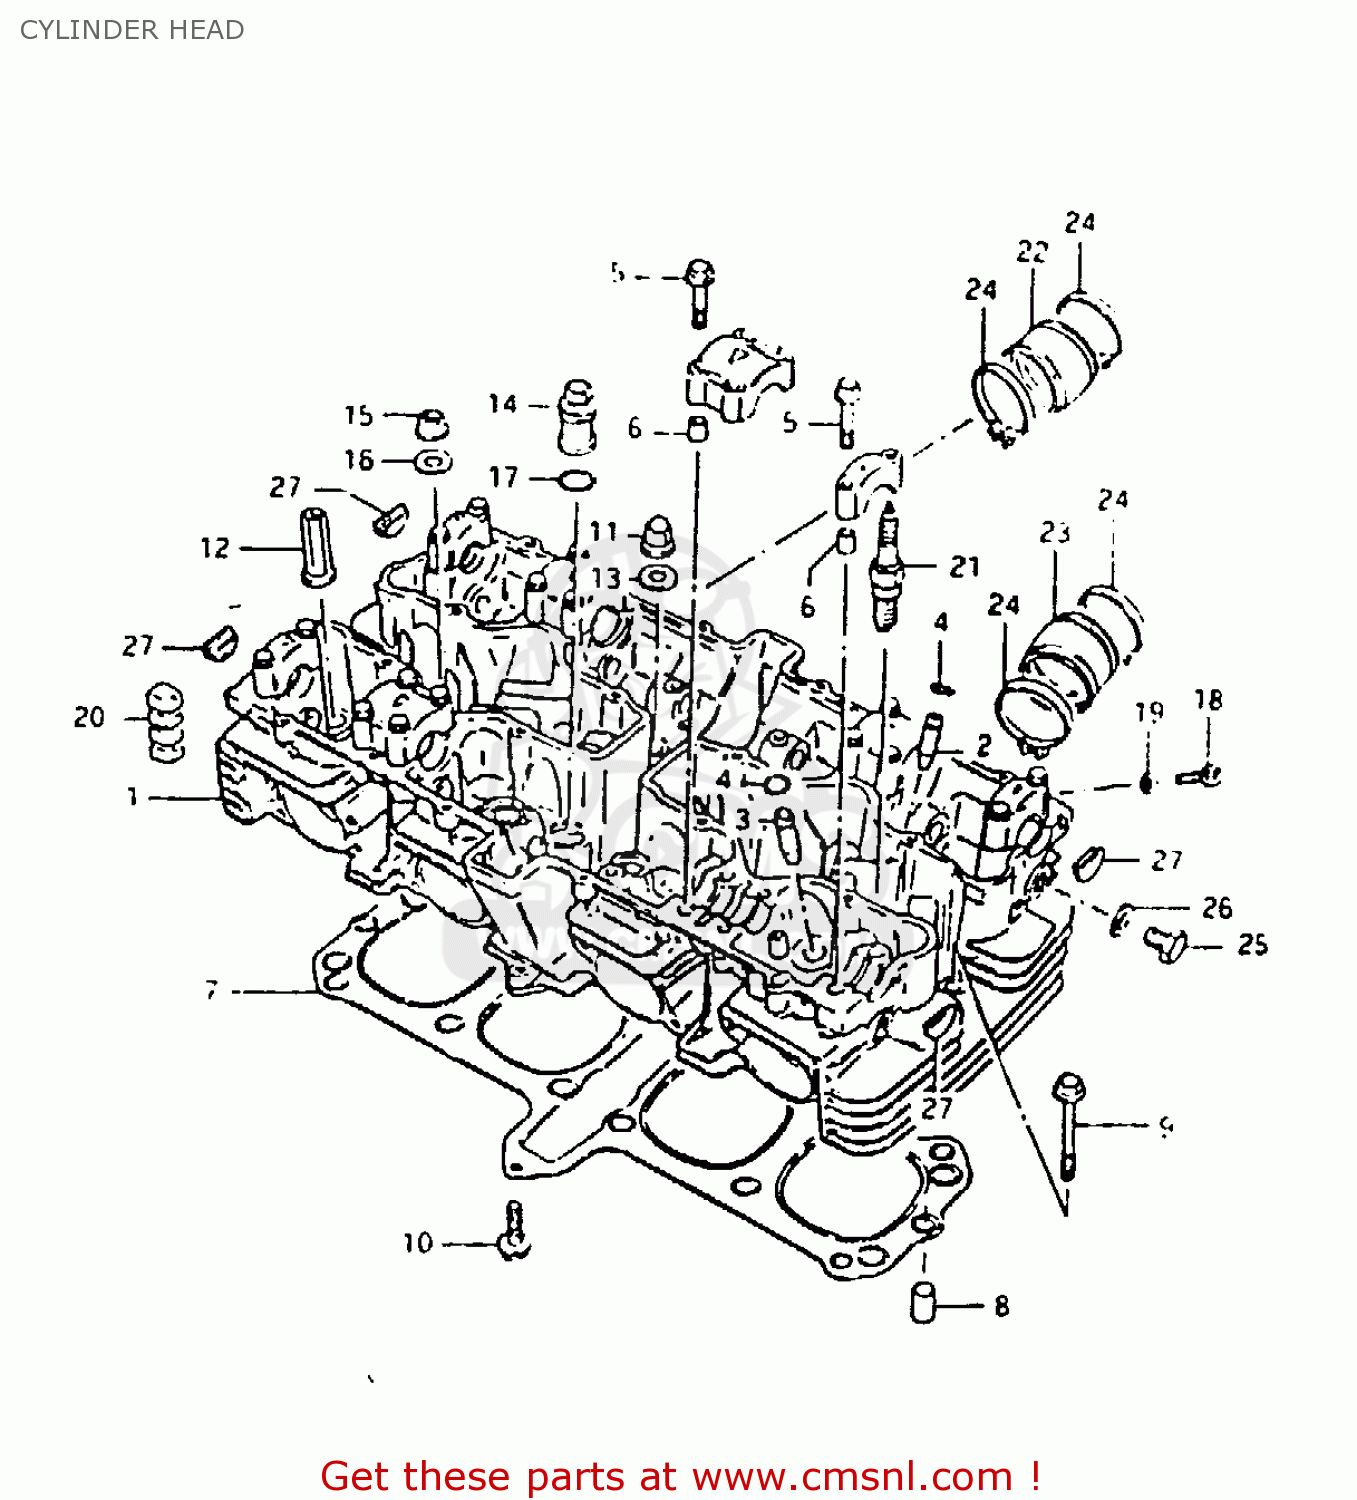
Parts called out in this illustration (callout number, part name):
1	CYLINDER HEAD SET
2	GUIDE,INTAKE VALVE
3	GUIDE,INTAKE VALVE
4	RING,SNAP
5	BOLT(6X39)
6	PIN(6.2X8X11)
7	GASKET (NAS)
8	PIN
9	BOLT
10	BOLT
11	NUT
12	NUT
13	GASKET (NAS)
14	NUT,CYLINDER HEAD SEAL
15	NUT
16	WASHER(10.5X22X2.3)
17	O RING(D:2.4,ID:16.8)
18	BOLT
19	GASKET(5.3X9.3X1.2) (NAS)
20	PAD,CYLINDER
21	SPARK PLUG DR8ES-L
22	PIPE,INTAKE,R
23	PIPE,INTAKE,L
24	CLAMP
25	PLUG (14X12)
26	GASKET(14X19.2X2) (NAS)
27	PLUG
